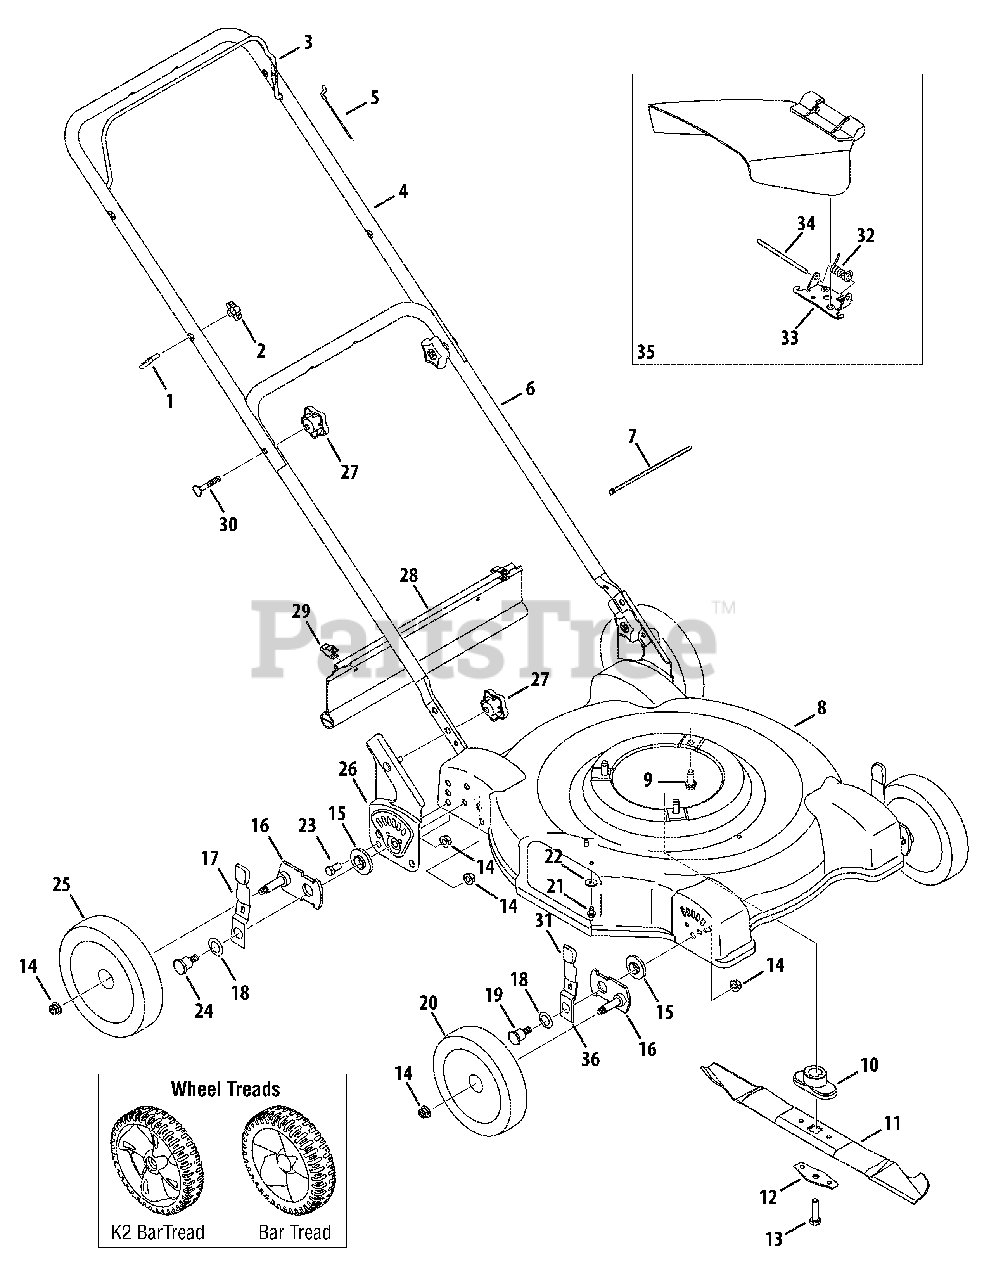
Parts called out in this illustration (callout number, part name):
1	Eye Bolt
2	Wing Nut
5	Blade Control Cable - 37.25 Inch
5	Blade Control Cable - 48.25 Inch
5	Blade Control Cable - 40.00 Inch
7	Cable Tie
9	TT Screw, 3/8-16 x 1.0
10	Blade Adapter, #6 x 1.19 W/Star
10	Blade Adapter, 25mm x 1.19
11	Standard Blade - 22 Inch
12	Blade Bell Support
13	Screw, 3/8-24 x 1.5
14	Lock Nut, 3/8-16
15	Height Adjuster Bearing
16	Pivot Arm
17	Lever Assembly
18	Bell Washer, .760 ID x 1.25 OD
19	Shoulder Screw
20	Front Wheel, 7 x 1.8, K2 Bar
20	Front Wheel, 7 x 1.8, Bar
21	TT Screw, 1/4-20 x .5
22	Bell Washer, .265 ID x .75 OD
23	Screw, 3/8-16 x .75
24	Shoulder Screw
25	Rear Wheel, 8 x 1.8, K2 Bar
25	Rear Wheel, 8 x 1.8, Bar
27	Star Knob
28	Trailshield
29	Hinge Clip
30	Carriage Bolt, 5/16-18 x 2
31	Knob
32	Torsion Spring
33	Chute Hinge
34	Hinge Pin
35	Hinged Chute Deflector Assembly
36	Spring Lever
